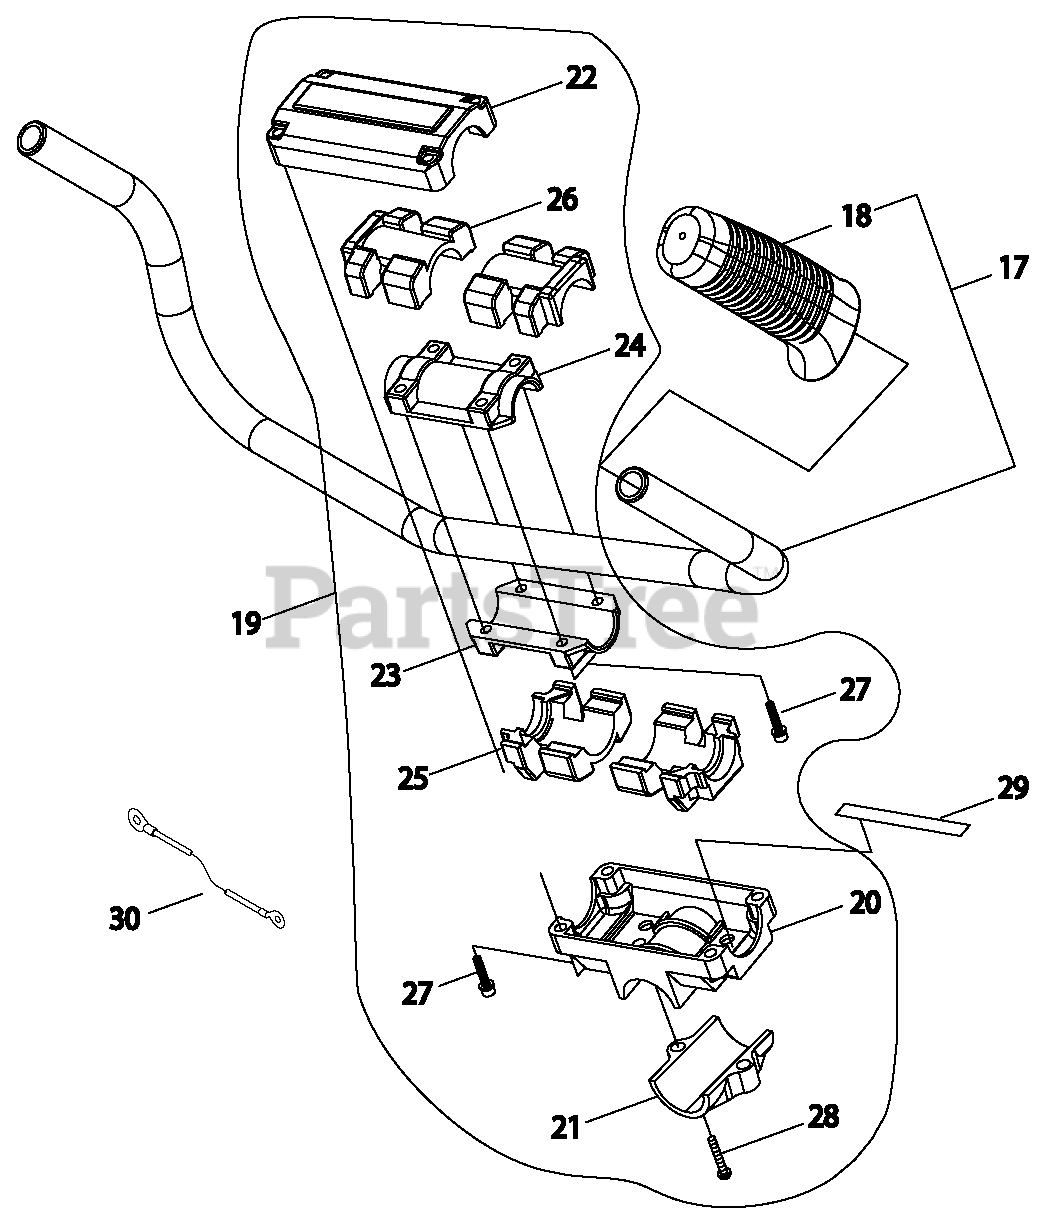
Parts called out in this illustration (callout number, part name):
17	HANDLEBAR ASSY
18	GRIP
19	BRACKET KIT, HANDLEBAR
20	BRACKET, HANDLE Ø28
21	CLAMP, LOWER Ø28
22	CLAMP, UPPER
23	CLAMP, LOWER
24	CLAMP, UPPER
25	CUSHION, LOWER
26	CUSHION, UPPER
27	BOLT M5×25
28	SCREW M6×25
29	LEAD - GROUND
30	LEAD - GROUND
